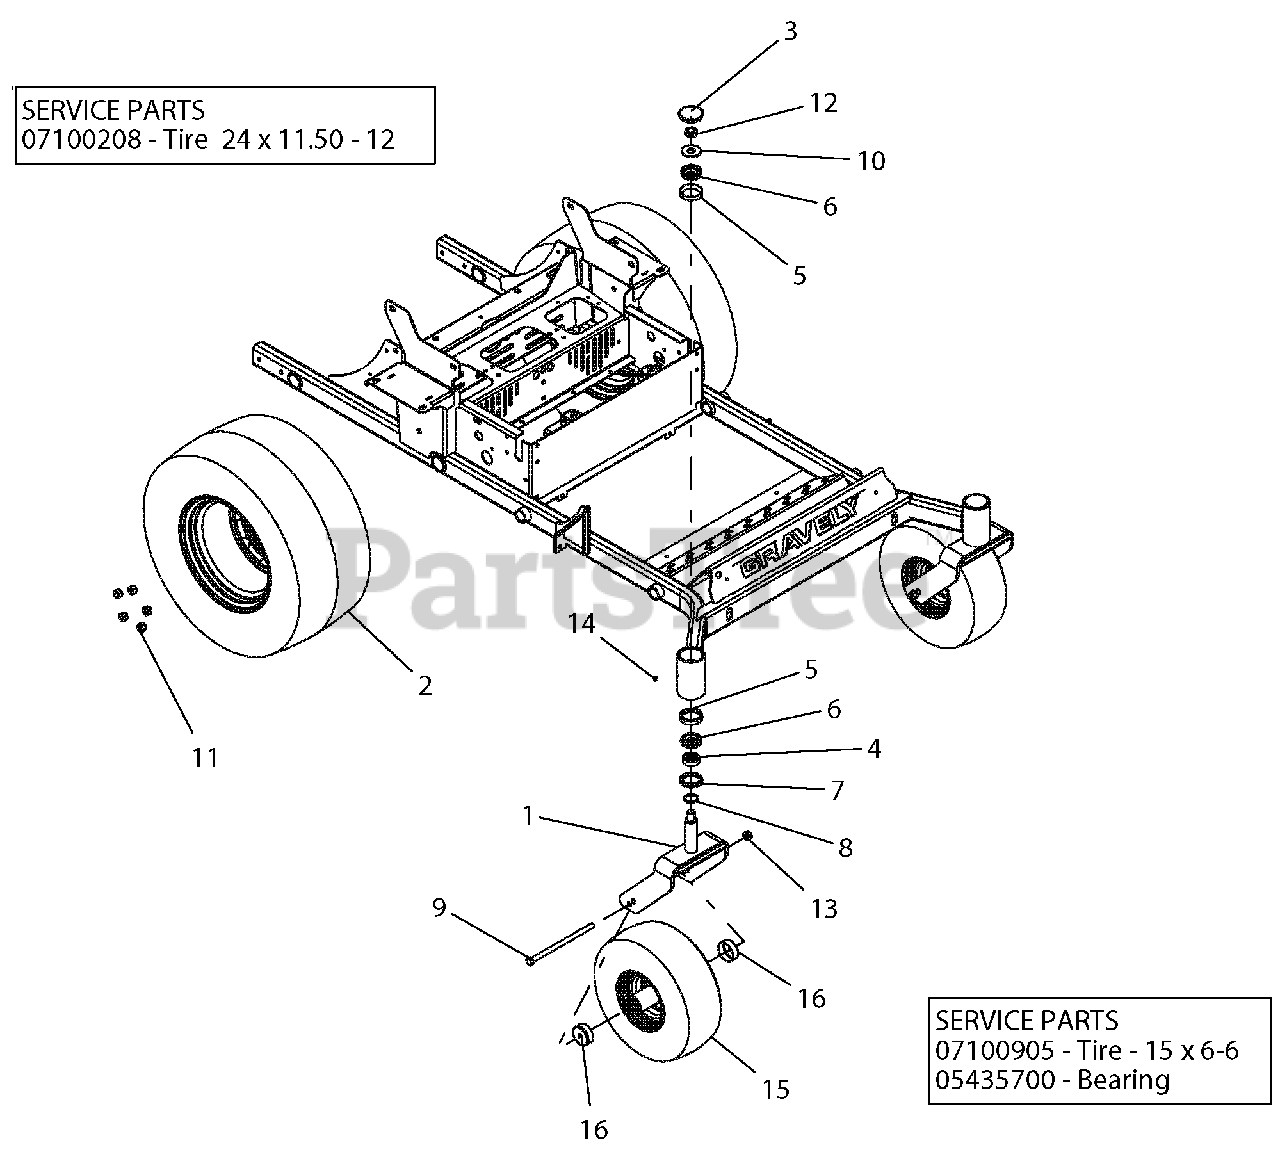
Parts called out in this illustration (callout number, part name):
1	WMT, CASTER FORK - RED
2	TIRE/WHEEL ASSY, 24X11.50-12
3	CAP, DUST
4	SPCR, FRONT CASTER FORK
5	BRG, CUP 2.328 X .465
6	BRG, CONE 1.250 X .660
7	SEAL, OIL 1.75 X 2.332 X .312
8	O-RING, .139 W X 1.234 ID
9	BLT-HEX .50-13X9.00 GR5 YWZC
10	WSHR-FL-STL.812X2.00X.148YWZC
11	NUT, LUG .500-13
12	@NUT-LK-CTR-JAM .75-16 YWZC
13	NUT, LK-TOP-FLG .50-13 YWZC
14	PLUG, .250-28 X .185 HEX HEAD
15	TIRE/WHEEL, 15 X 6.00-6 SMOOTH
16	SHIELD, WHEEL BEARING
